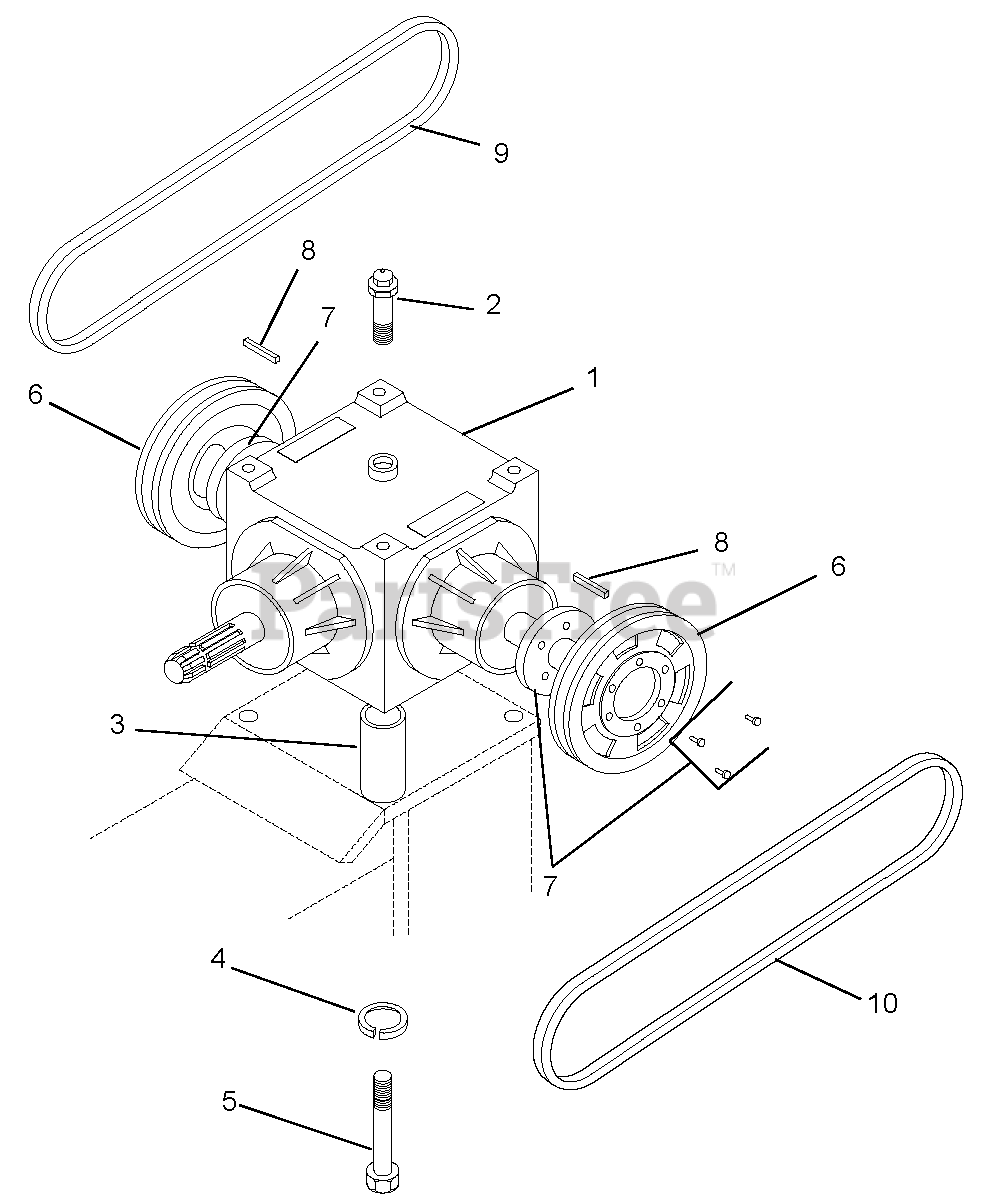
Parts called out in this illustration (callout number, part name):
1	Gearbox Assembly
2	Plug, Valve Vent
3	MOUNTING SPACER, GEAR BOX
4	Washer, Lock .50
5	Cap Screw, Hex Head .50-13 x 3
6	Pulley, 1-Belt 7.0 PD
7	Bushing 1.125
8	Key .25 x .25 x 2.00
9	V-Belt BX78
10	BELT-V BX70 (ALSO 5 50022451
